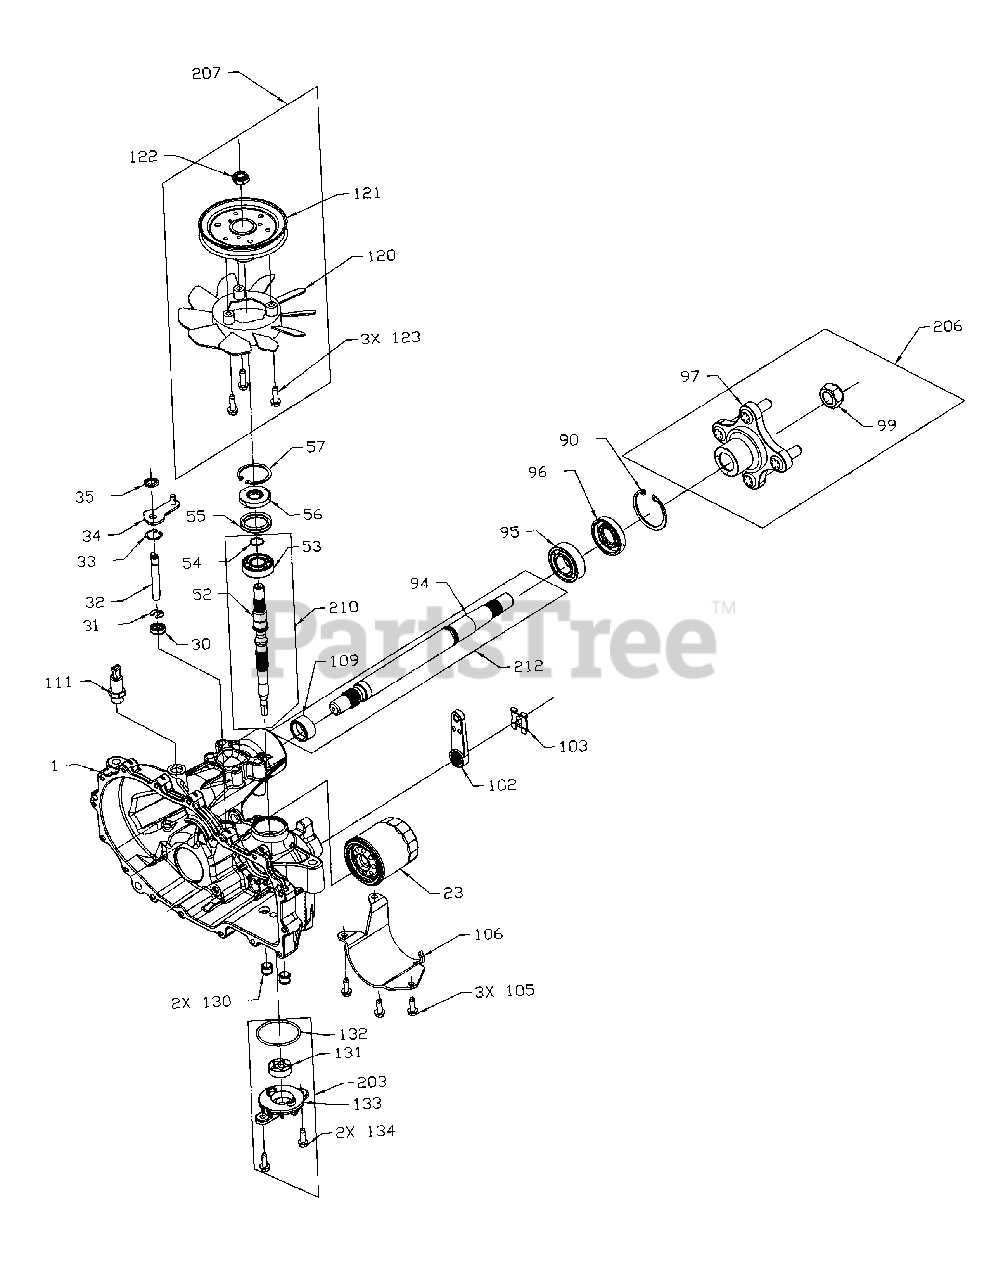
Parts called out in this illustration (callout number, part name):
1	Kit, Housing Main LH Chrg includes
1	Housing, Main LH Chrg
2	Kit, Cover Side LH includes
2	Cover, Side LH
2	Gear
7	HFHCS 1/4-20 x 1.25''
11	Plug 9/16/18 (Metal)
20	Center Section, LH Chrg
22	Plate, Bypass
23	Filter, Oil
24	Shock Valve
26	Seal, Plug 1.250 x .250
27	HFHCS 3/8-16 x 1.5 (Patch)
30	Seal, Lip .375 x .75 x .25
31	Ring, Ret .375 External
32	Rod, Bypass
33	Ring, Ret .750 Internal
34	Arm, Bypass
35	Ring, Rtng .375 Ext
40	Trunnion, Swashplate
41	Seal, Lip 18 x 32 x 7
44	Arm, Control - RH
45	Washer .34 x .88 x .06
46	TWHCS 5/16-24 x 1.00 (Patch)
52	Shaft, Input
54	Ring, Ret Wire .561 ID
55	Washer 1.23 x 1.56 x .04
56	Seal, Lip 17 x 40 x 7
57	Ring, Ret 2.06 Internal
60	Bearing, Thrust
64	Cylinder Block Assembly 16cc
65	Bearing, Thrust Ball 30 x 52 x 13
69	Block 7 Piston Assembly
70	Washer .63 x 1.0 x .05
71	Ring, Ret 62 External
73	Shaft, Motor
74	Washer .72 x 1.16 x .04
80	Washer .5 x 1.0 x .03
81	Gear, 45T
83	Jack Shaft (Pin)
90	Ring, Ret 2.06 Internal
91	Gear, 54T
92	Spacer, .750 x 1.32 x .257
93	Bearing Ball .75 x 40 x 12
94	Shaft, Axle
95	Bearing Ball 1.0 x 52 x 15 Open 6205M
96	Seal, Lip TC4
97	Hub, 4 Stud
99	Nut, Hex Lock 3/4-16
100	Pawl, Brake
101	Shaft, Brake
102	Handle, Brake
103	Clip, Retaining
105	HFHCS 1/4-20 x .75
106	Guard, Filter - LH
111	Fitting, Str 9/16-18 SAE .5 Barb
120	Fan, 7'', 10 Blade
121	Pulley 4.5 Inch
122	Nut, Hex Lock 1/2-20 Nylon
123	HFHCS 1/4-20 x .75
130	Tube, Connecting
131	Gerotor Assembly (1.6 cc/rev)
131	KIT, GEROTOR SEAL PARTS
132	O-Ring, -137, 0.103 x 2.050
133	Cover, Charge Pump
134	HFHCS 1/4-20 x .75
140	Spacer, .320 x 1.005 x .179
141	Arm, Neutral Left
142	KIT, RTN SCREWS
145	Assembly, RTN
147	Spring, Extension
148	Bracket Damper
200	Kit, Seal
201	Kit, Center Section, LH Chrg
202	Kit, Chrg Relief
203	Kit, Charge
206	Kit, Hub 4 Bolt
207	Kit, Fan/ Pulley
209	Hub Puller, 4 Bolt
210	Kit, Input Shaft
211	Kit, RTN Bidirectional
212	Kit, Axle Shaft
